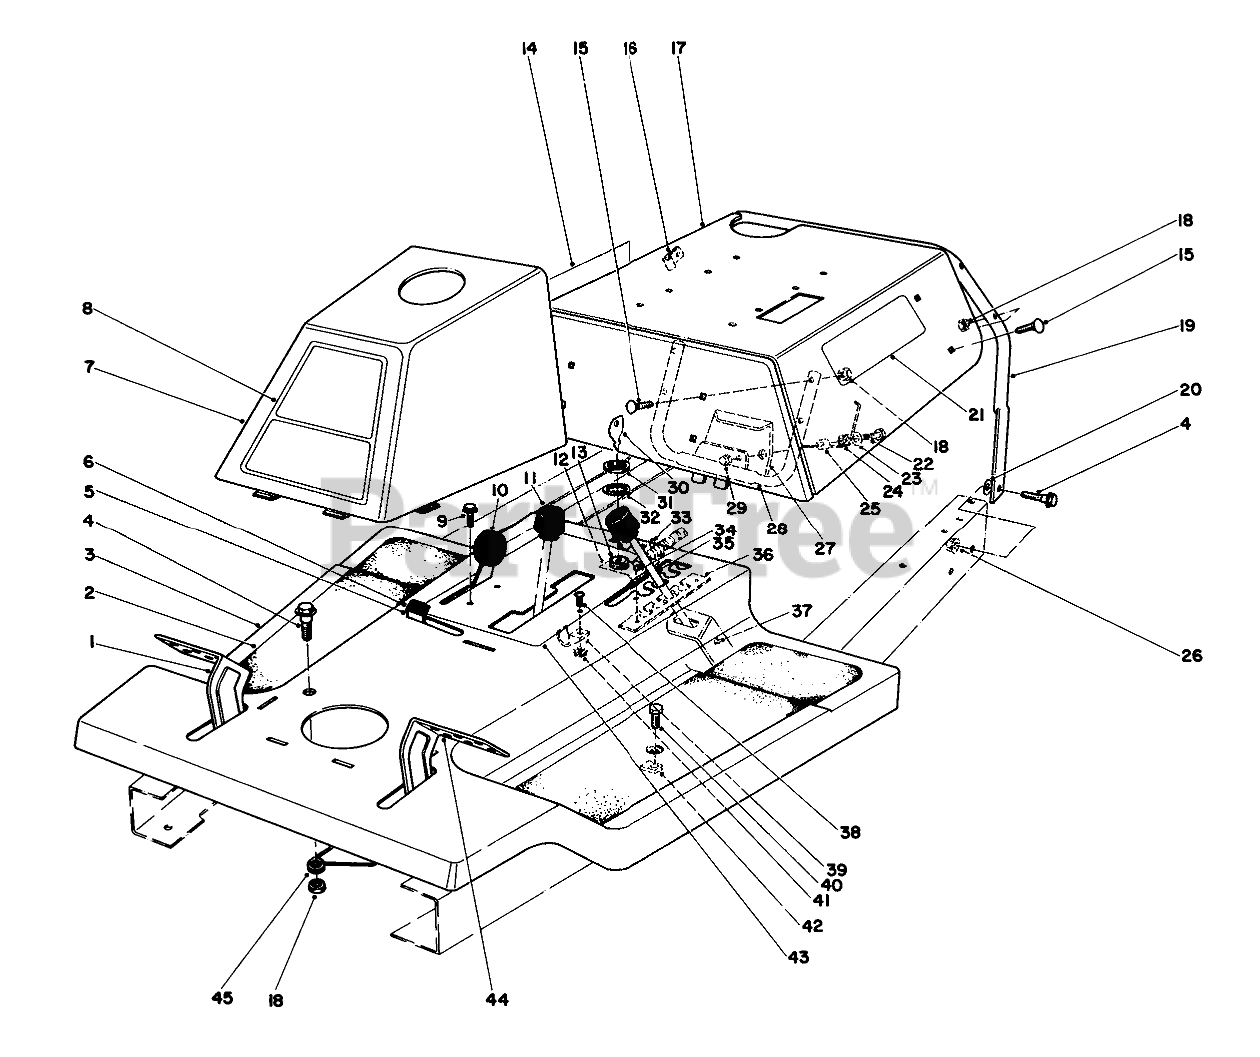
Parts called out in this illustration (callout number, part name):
1	Brake Pedal
2	TREAD-FOOT
3	Front Body Assembly (Incl. Ref. #34, 36 & 43)
4	SCREW-SHOULDER
5	Parking Brake
6	TIP-PARKING BRAKE
7	Tower
8	Decal-725
9	8X1/2 SELF TAP SCREW
10	THROTTLE CONTROL ASM
13	Switch Starter (Incl. Ref. #30-32)
14	Decal Shift Pattern
15	BOLT-CARR
16	CLIP-FUEL LINE
17	Body-Rear
18	NUT-LOCK, CONE
19	Support-Rear Body
20	WASHER-PLAIN
21	Decal
22	SCREW-HH
23	WASHER-FLAT
24	Spring-Latch
25	LATCH SPACER
26	NUT-HF
27	Latch
28	Front Support
29	NUT-CAP
30	Key
31	NUT-HH
32	WASHER-TOOTH, INTERNAL
33	TIE-CABLE
34	RIVET-POP
35	Height of Cut Lever
36	Height Adjustment Plate
37	PIN-ROLL
39	WIRE CLAMP
40	SCREW-HH
41	NUT-KEPS
42	NUT-TINNERMAN
43	Decal-Front Body
44	Clutch Pedal
45	SPRING-PARKING BRAKE
